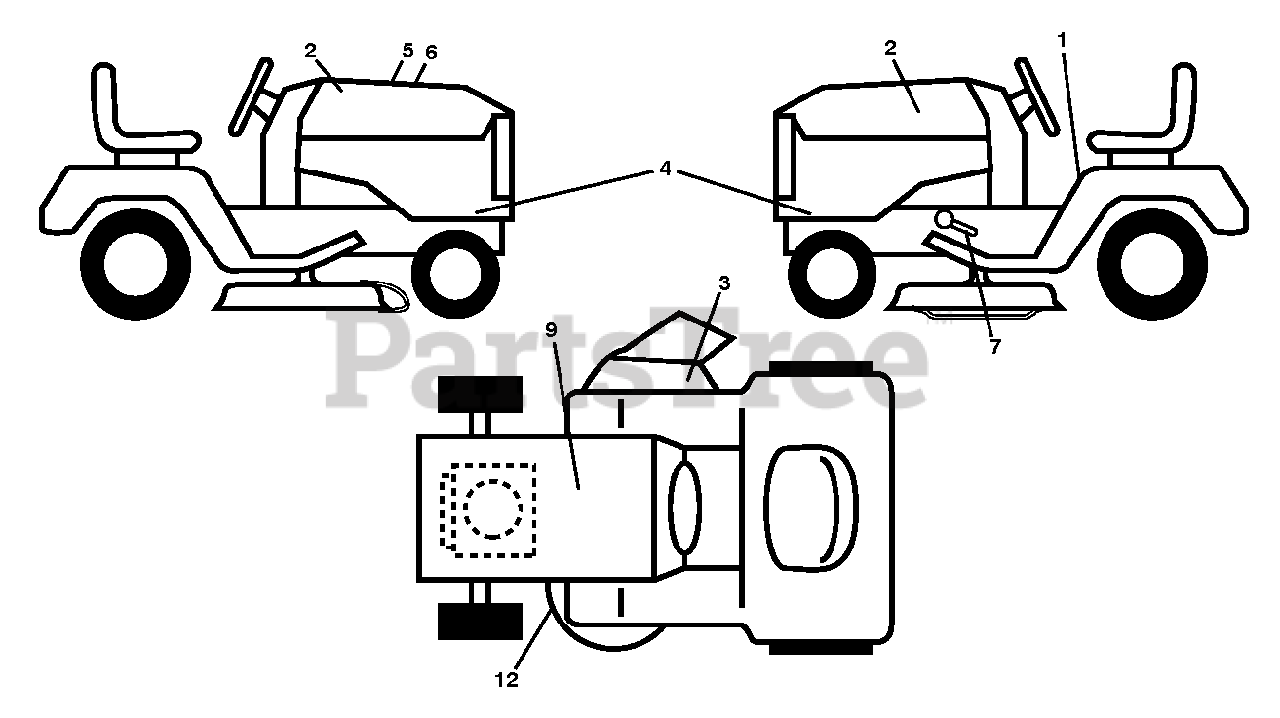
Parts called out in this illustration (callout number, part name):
1	DECAL.FENDER.WARNING
2	RP.DECAL.BADGE.170MM.TEXTLOGO
3	DECAL.WARN.KEEP.HAND.AWAY
4	DECAL.SDPNL.GT2.YT46LS.SET
5	DECAL.WARNING.CUST.RESP.E85.
7	DECAL.PEDAL.HUSQ.CROWN
9	DECAL BTRY SYMBOLS
12	DECAL V BELT SCHEMATIC
